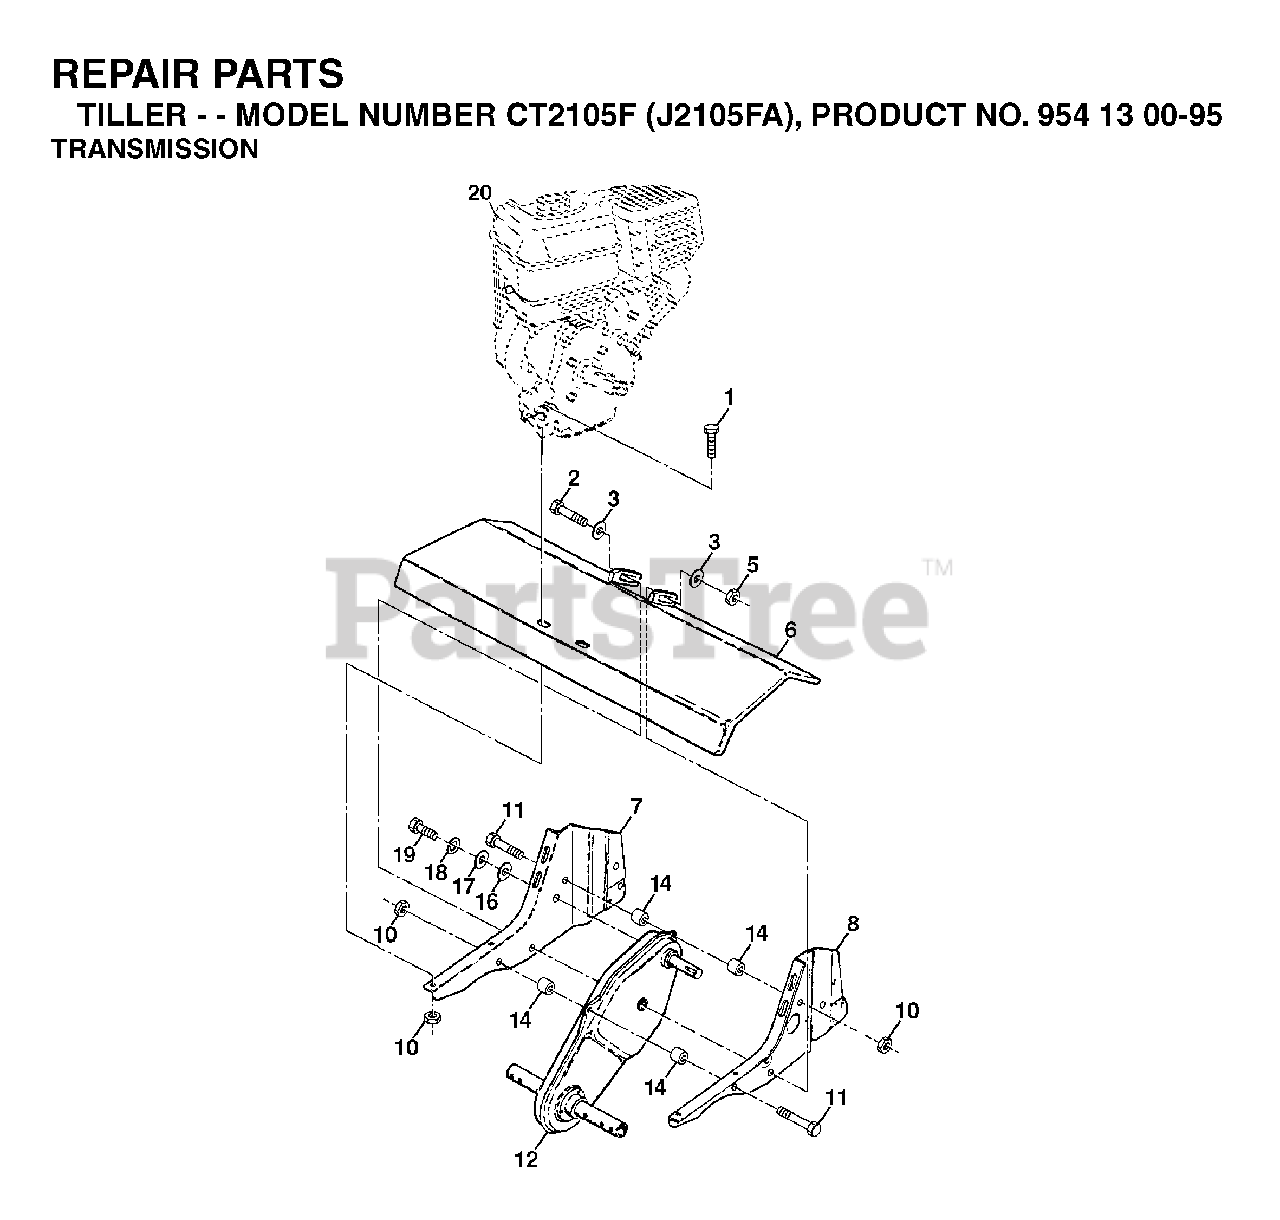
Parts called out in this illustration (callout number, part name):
1	BOLT
3	WASHER
5	NUT
10	LOCKNUT-FLANGE 5/16-18
11	BOLT
18	LOCKWASHER
